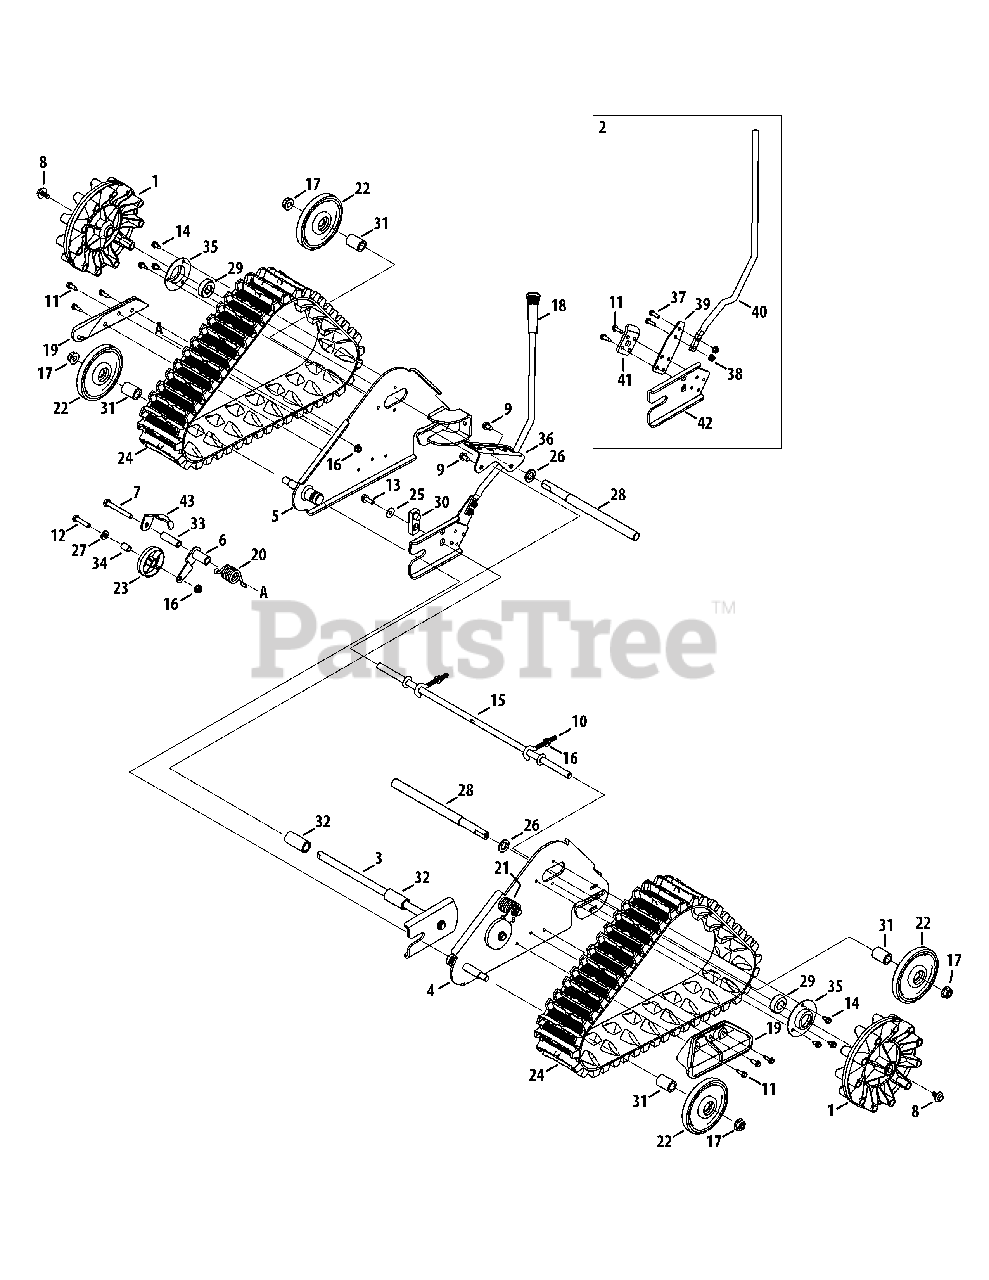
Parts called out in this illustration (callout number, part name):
1	Track Drive Wheel
2	Height Adjustment Lever Ass'ly
3	Pivot Bracket Assembly
4	Track Mount Plate Assembly, LH
5	Track Mount Plate Assembly, RH
6	Pivot Tension Bracket Assembly
7	Hex Screw, 5/16-18, 2.50, Gr5
8	Screw, 5/16-24 x .750
9	Hex Washer Screw, 5/16-18 x .875
10	Eye Bolt, 5/8 x 2.375, 5/16-18
11	Hex Washer Screw, 1/4-20 x .625
12	Hex Cap Screw, 5/16-18 x 1.50
13	Hex Washer Screw, 5/16-18 x .875
14	Hex Washer Screw, 1/4-20 x .625
15	Rear Wheel Axle
16	Nut, Flange lock, 5/16-18
17	Flange Lock Nut, 1/2-13
18	Grip, .5 ID x 3.45
19	Track Skid
20	Torsion Spring
21	Torsion Spring
22	Wheel, 5.00 OD
23	Track Tension Wheel
24	Track, 61mm x 22 Pitches
25	Washer, Bell, .340 x .872
26	Flat Washer, .672 x 1.125 x .125
27	Flat Washer, .344 x .750 x .120
28	Axle, .75 OD x 11.06 LG
29	Ball Bearing, 17 x 40 x 12
30	Height Adjustment Adapter
31	Spacer, .63 x 1.00 x 1.42
32	Spacer, .632 x 1.00 x 1.42
33	Sleeve, .33 x .50 x 1.73
34	Sleeve, .33 x .50 x .75
35	Cup Bearing
36	Height Adjustment Index Bracket
37	Hex Cap Screw, 1/4-20 x .75
38	Nut, Flangelock, 1/4-20
39	Lever Mounting Bracket
40	Height Adjustment Lever
41	Lever Pivot Bracket
42	Height Adjustment Pivot Bracket
